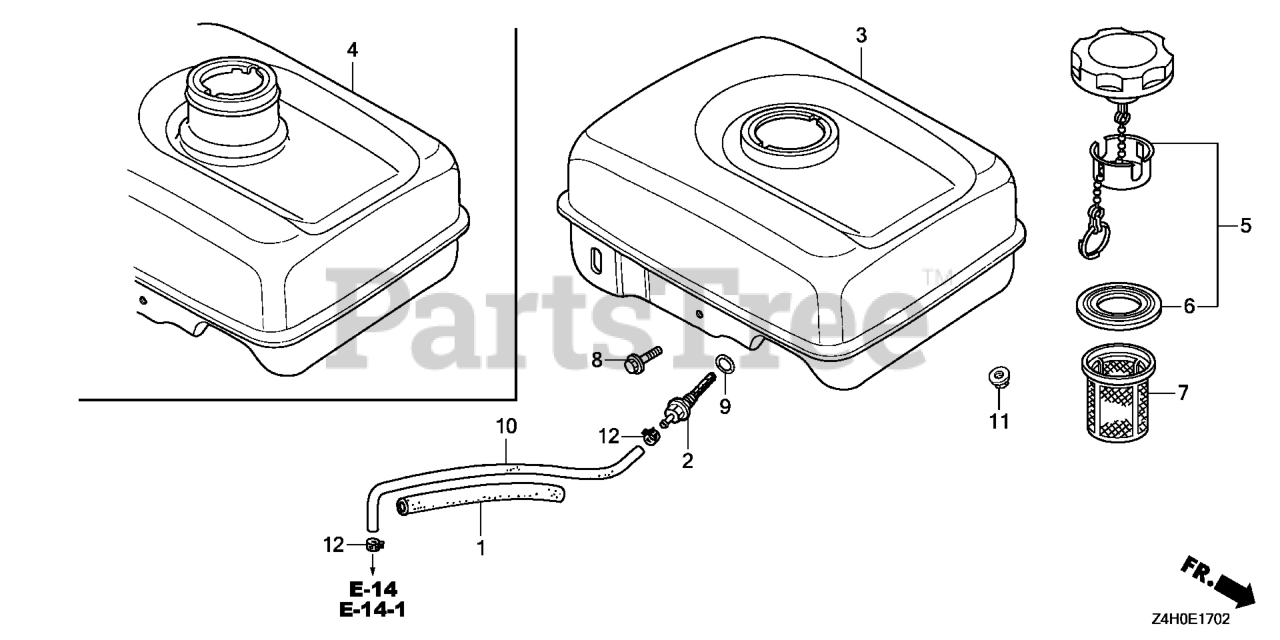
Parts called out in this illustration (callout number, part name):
1	RUBBER, SUPPORTER (107MM)
2	JOINT, FUEL TANK
3	TANK, FUEL *NH1* (GAUGELESS) (BLACK)
5	CAP, FUEL FILLER
6	GASKET, FUEL FILLER CAP
6	GASKET, FUEL FILLER CAP (39X62X3) (TOUYOUSYA)
8	BOLT, FLANGE (6X29)
9	O-RING (14MM) (ARAI) Use up to Engine SN 2949254.
10	TUBE, FUEL (4.5X140) (FKM)
10	TUBE, FUEL (4.5X140)
11	NUT, FLANGE (6MM)
12	CLIP, TUBE (D8)
